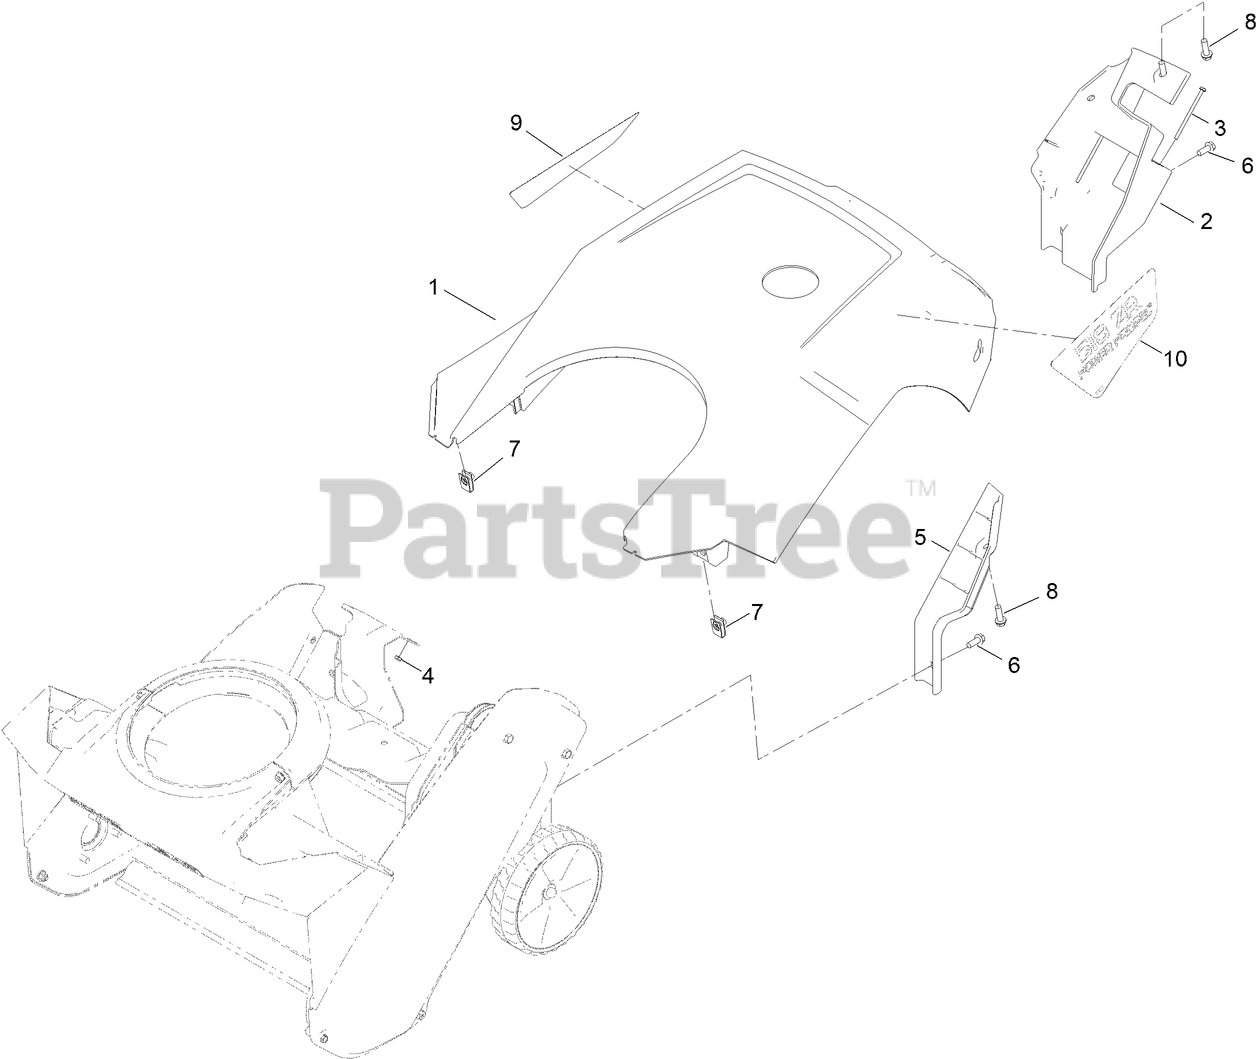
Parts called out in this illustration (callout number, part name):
1	SHROUD-UPPER
2	SHROUD-LOWER, RH
3	SCREW-HWH
4	NUT-HEX
5	SHROUD-LOWER, LH
6	SCREW-HWH
8	SCREW-PLASTITE, HWH
9	DECAL-RH SHROUD ZE
10	DECAL-LH SHROUD ZE
